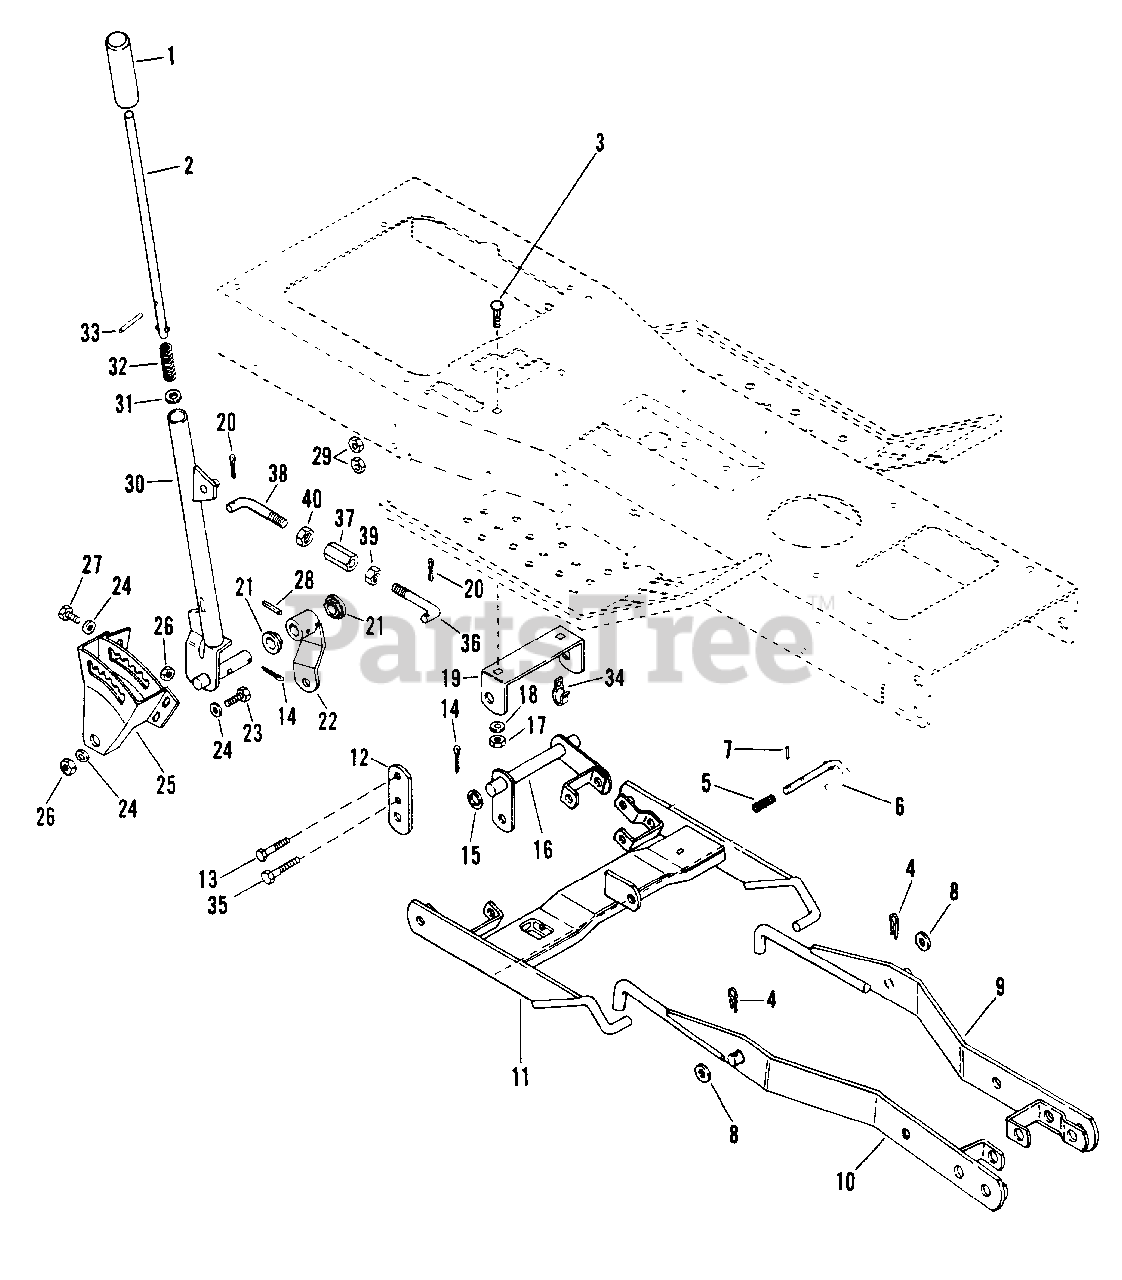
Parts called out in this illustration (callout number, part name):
1	GRIP
2	ROD, PLUNGER
3	BOLT, CARRIAGE 3/8-16X.75
4	HAIRPIN, INTERNAL
5	SPRING, COMPRESSION
6	PIN, LATCH
7	PIN, SPRING .125X.750
8	WASHER, FLAT .500X1.250X.083
9	ARM, LIFT L.H.
10	ARM, LIFT R.H.
11	HANGER, REAR
12	BRACKET, HANGER
13	BOLT, HEX 3/8-16X.75
14	PIN, COTTER .125X1.500
15	WASHER, FLAT .813X1.37X.100
16	LEVER, CENTER LIFT
17	NUT, HEX 3/8-16
18	WASHER, LOCK 3/8 REG.
19	BRACKET, CENTER LIFT
20	PIN, COTTER .125X1.00
21	BUSHING, FLANGE
22	ARM, LIFT
23	BOLT, HEX 5/16-18X1.25
24	WASHER, FLAT .312X.734X.065
25	QUADRANT, LIFT
26	NUT, LOCK 5/16-18
27	BOLT, HEX 5/16-18X.75
28	PIN, GROOVE 1/4
29	NUT, LOCK 3/8-16
30	HANDLE, LIFT
31	WASHER, FLAT .469X.938X.065
32	SPRING
33	PIN, SPRING .250X1.750
34	J-CLAMP
35	BOLT, HEX 3/8-16X1.00
36	LINK, LIFT R.H.
37	NUT, COUPLING
38	LINK, LIFT L.H.
39	NUT, JAM 1/2-13
40	NUT, JAM 1/2-13 L.H.
